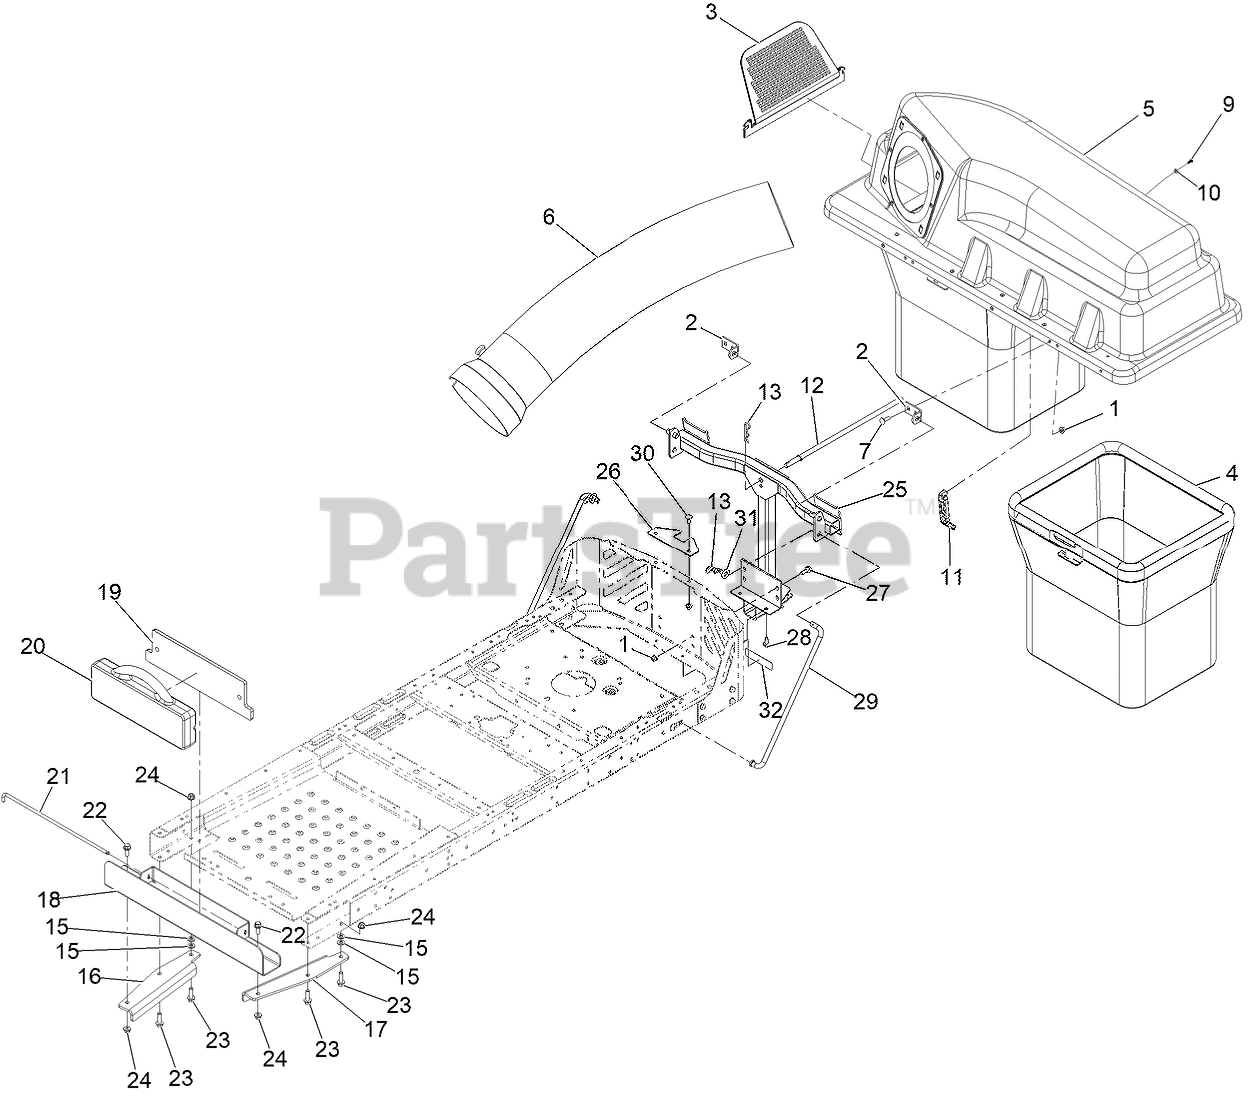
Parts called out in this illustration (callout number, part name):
1	NUT-HF, NI
2	BRACKET-PIVOT, HOPPER
3	SCREEN-BAGGER
4	BAG ASM
5	BAGGER TOP ASM
6	TUBE-BAGGER
7	BOLT-CARR
9	SCREW-PLASTIC, PTH
10	WASHER-FLAT
11	LATCH-RUBBER
12	ROD-HOOD, DOWN (HOLD)
13	PIN-HAIR
15	WASHER-FLAT
17	BRACKET-BAGGER WEIGHT, LH
18	CHANNEL-WEIGHT, BAGGER
20	WEIGHT-35 POUND
21	PIN-WEIGHT
22	SCREW-HHF 3/8-16 X 1
23	SCREW-HHF
24	NUT-HF, NI
25	Frame ASM, Pivot [black]
26	BRACKET-STABILIZER
27	SCREW-HHF
28	Screw-HWH 5/16-18 X 3/4 Tf
29	ROD-SUPPORT
30	BOLT-CARR
31	WASHER-FLAT
